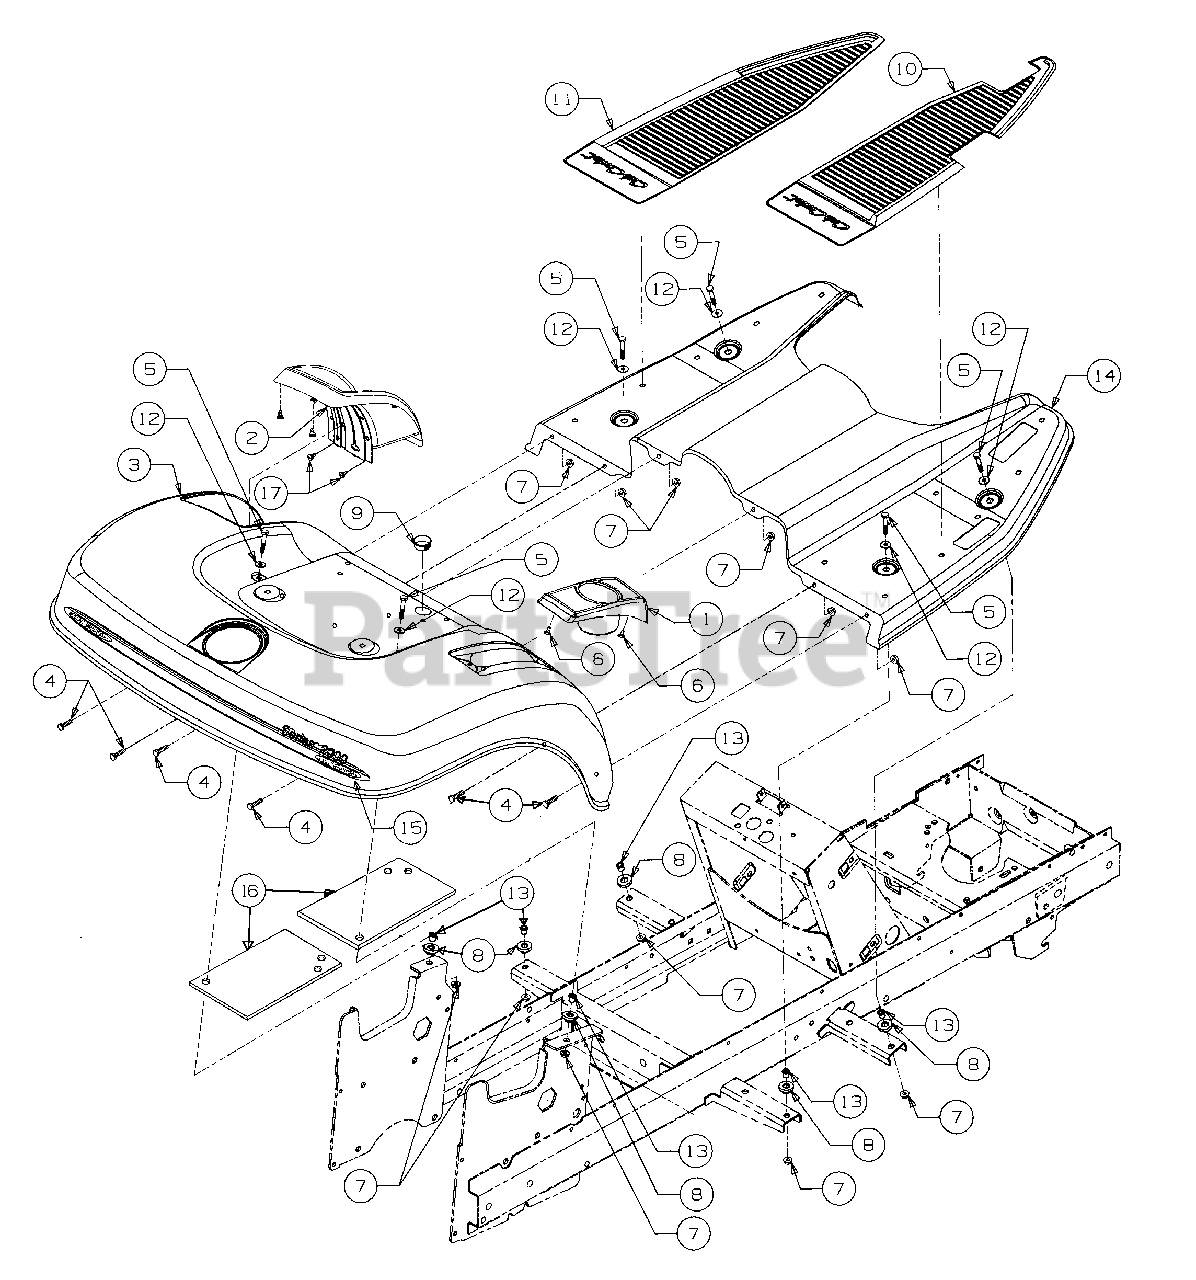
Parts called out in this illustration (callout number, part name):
1	Cup Holder
2	Cover, Implement Lift
3	Fender
4	Screw, Hex Cap, 1/4-20 x .62
5	Screw, Hex Cap, 1/4-20 x 1.0
6	Screw, Hex Tapp, #10 x .38 Lg
7	Nut, Hex Flange Lock, 1/4-20 1
8	Grommet, Insulator
9	Bushing, Snap, 7/8 ID
10	Pad, RH Foot
11	Pad, LH Foot
12	Washer, Flat, .255 x .72 x .06
13	Spacer, .28 ID x .40 OD x .42 Lg
14	Running Board w/Graphic
15	Graphic, Rear Fender
16	Bracket, Fender Reinforcement
17	Screw, Hex Tapp, #10 x .38 Lg
